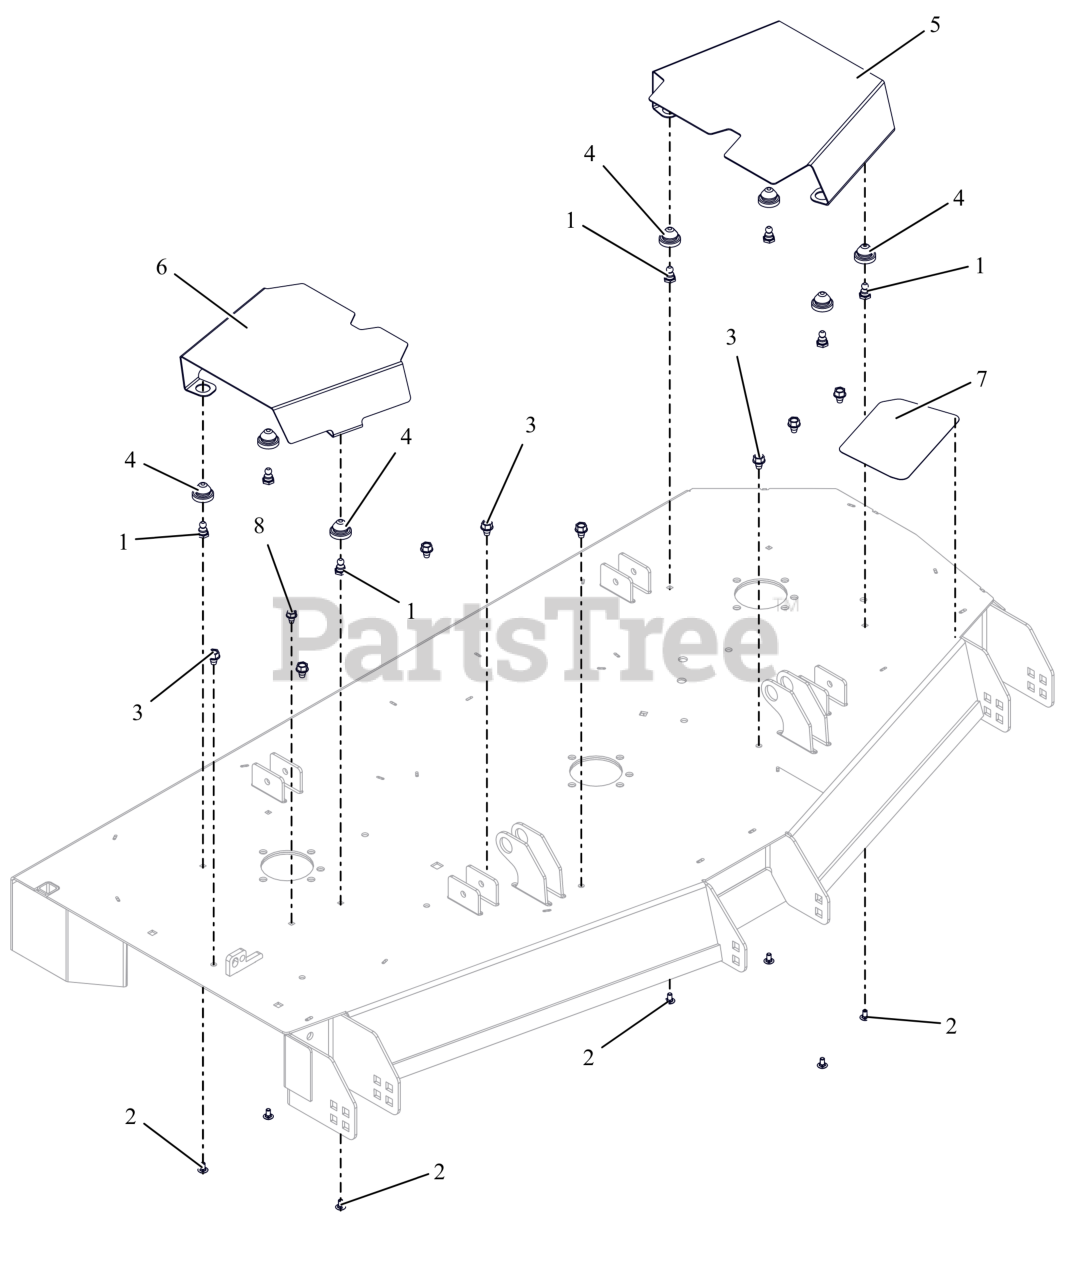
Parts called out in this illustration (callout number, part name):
1	STUD, BALL FEMALE .250-20 THREAD
2	BLT, RHSSN.25-20X.500 G5 ZCC
3	SCR,TAP .375-16X.50 HWH TR ZCC
4	COUPLING, RUBBER PUSH-IN
5	COVER- BELT 60" LEFT
6	COVER- BELT 60" RIGHT
7	GRIP, STEP ANTI SKID HD XF3
8	SCR,TAP .312-18X.50 HWH TR ZCC
